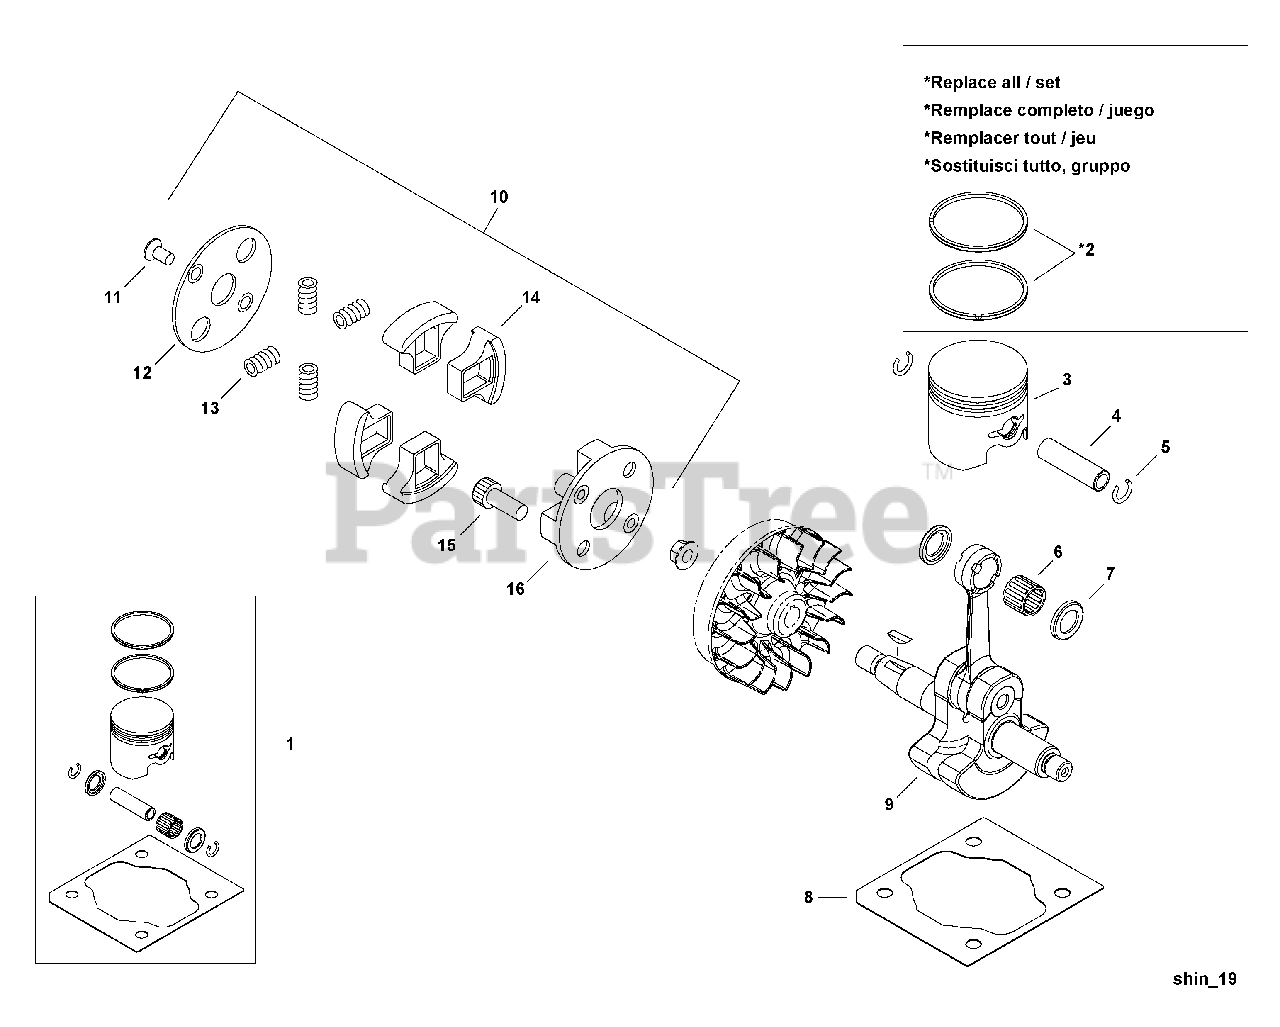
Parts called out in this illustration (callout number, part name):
1	PISTON KIT
2	RING, PISTON
3	PISTON
4	PIN, PISTON
5	RING, RETAINING
6	BEARING, NEEDLE
7	SPACER - 9
8	GASKET, CYLINDER
9	CRANKSHAFT ASSY
10	CLUTCH ASSY
12	PLATE, CLUTCH
13	SPRING, CLUTCH
14	SHOE, CLUTCH
15	BOLT, CLUTCH
16	HUB, CLUTCH
